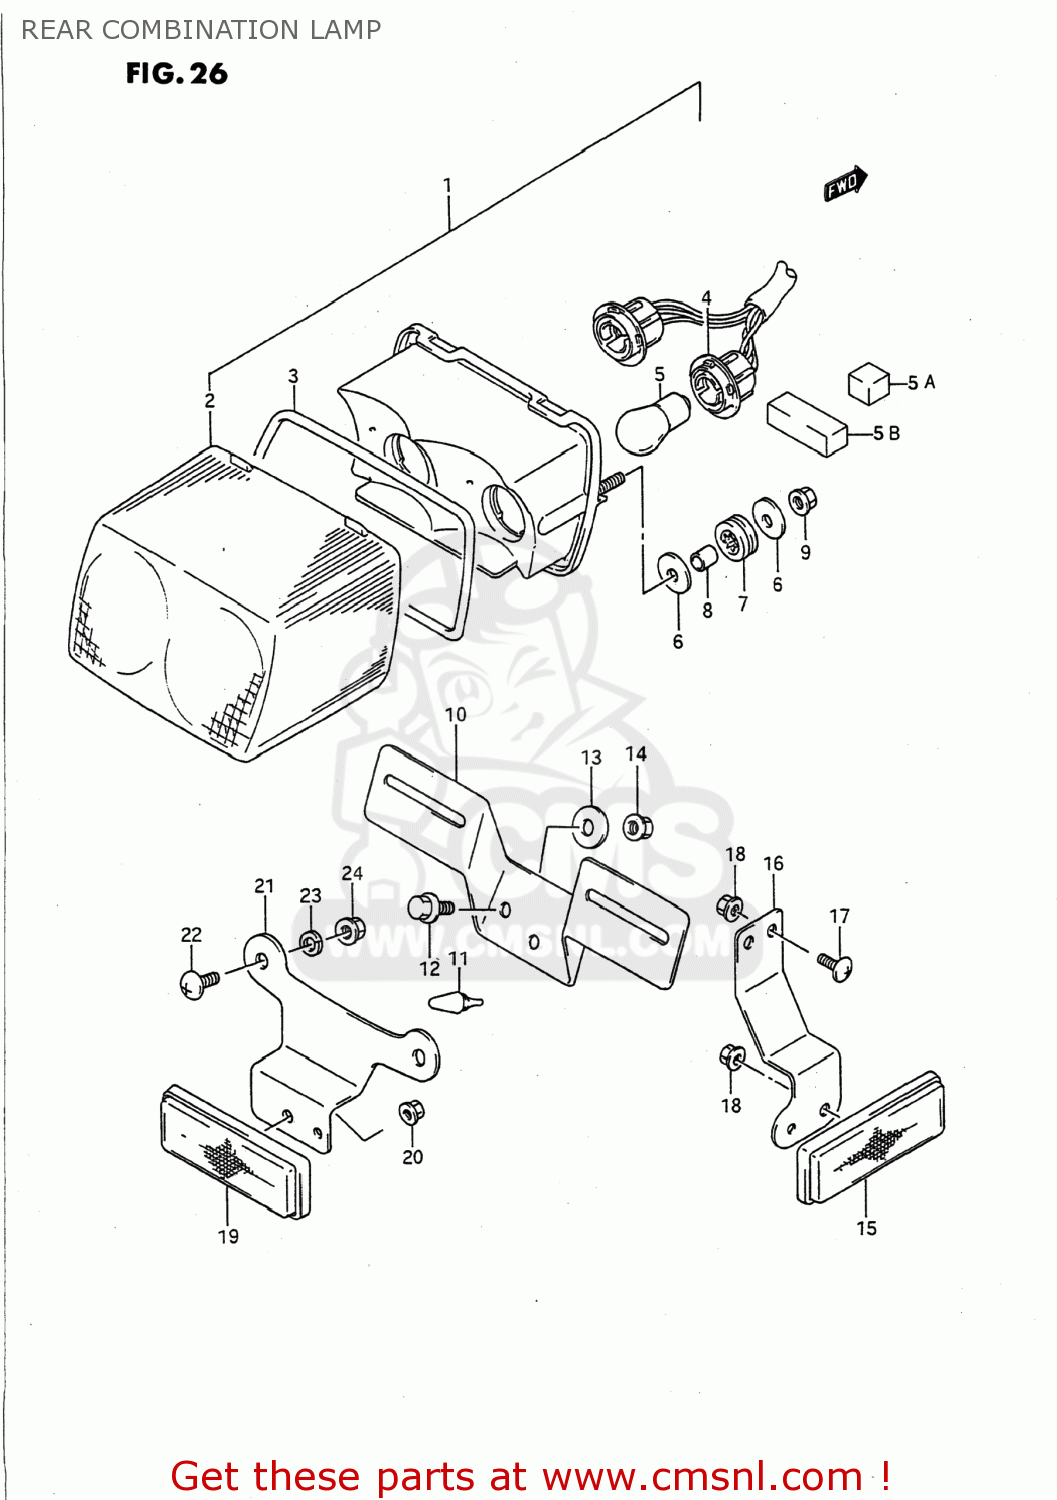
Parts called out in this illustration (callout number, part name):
1	LAMP ASSY,RR COMBINATION
2	LENS
3	GASKET (NAS)
4	SOCKET
5	BULB(12V21/5W)
5A	CUSHION,REAR COMBINATION LAMP
5B	CUSHION,REAR LENS
6	WASHER (6.5X20X1)
7	CUSHION
8	SPACER
9	NUT
10	BRACKET,LICENSE PLATE
11	CUSHION
12	BOLT
13	WASHER,COVER,FRONT
14	NUT
15	REFLECTOR ASSY,RR
16	SPACER
17	SCREW 5X12
18	NUT
19	REFLECTOR ASSY,RR
20	NUT
21	BRACKET,RR RR
22	SCREW 6X12
23	WASHER
24	NUT
